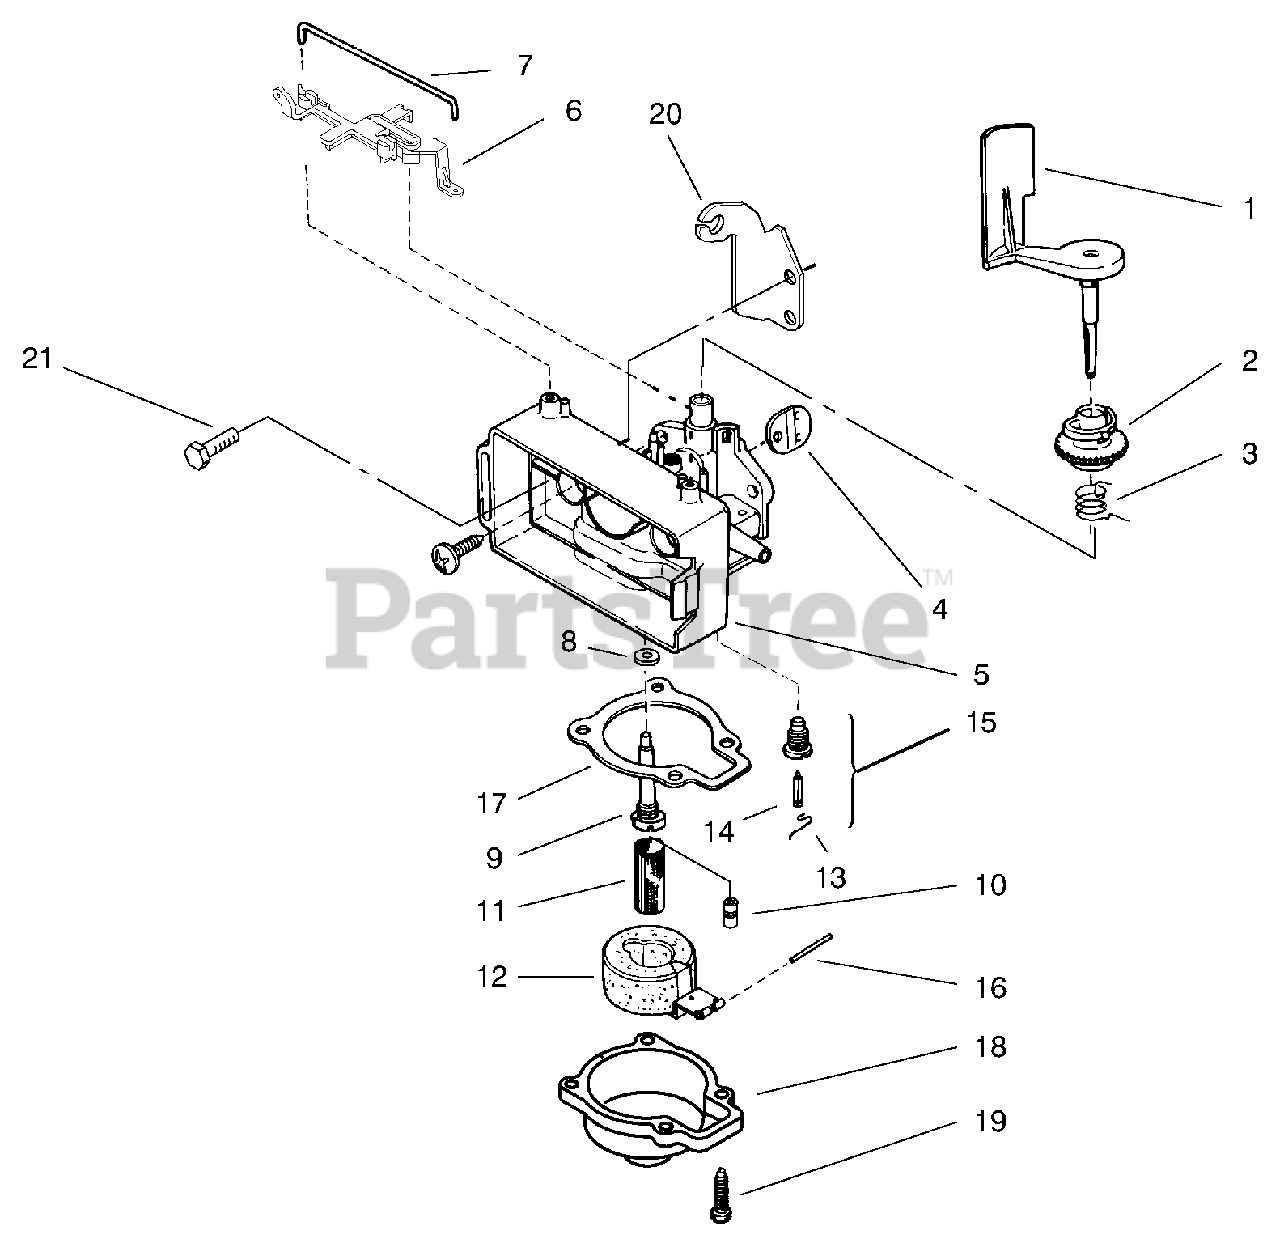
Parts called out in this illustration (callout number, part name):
1	Air Vane & Shaft
2	Collar Adjustment
3	Spring Governor
4	Disc Throttle
5	Carburetor Body
6	Lever-Speed Adjust
7	Retainer
11	Filter-Fuel
12	Float & Arm ASM
13	Clip
14	Float ASM
15	Seat ASM
17	Gasket-Float Chamber
18	Float Chamber
20	Throttle Control Bracket
